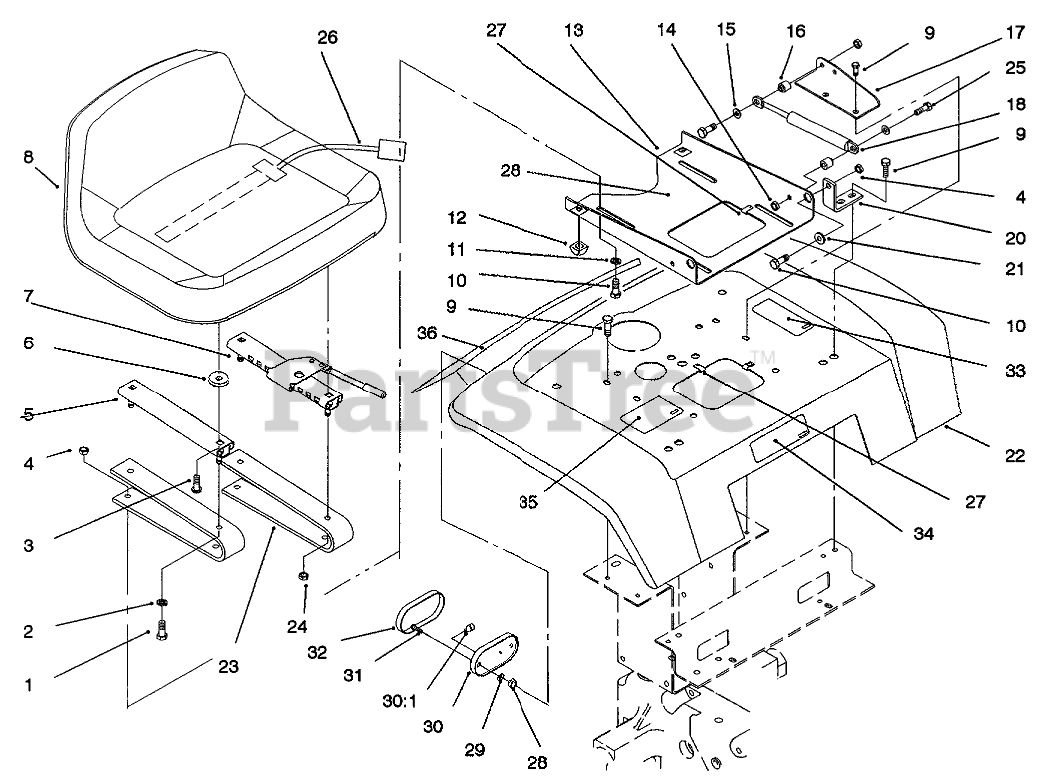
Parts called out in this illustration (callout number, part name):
1	SCREW-HH
2	WASHER-LOCK
4	NUT-LOCK, NI
6	SPACER-NYLON
8	SEAT
9	Bolt
10	SCREW-HH
11	WASHER-PLAIN
12	BUMPER SJ5514 BLACK
13	PLT-SEAT PIVT (BLACK)
14	NUT-HEX
15	WASHER-FLAT
16	SPACER
17	Bracket-Gas Spring
18	GAS SPRING
20	BRACKET-PIVOT
21	BUSHING
23	SPRING SEAT (BLACK)
25	SCREW-HH
26	SWITCH-SEAT
27	SPEED CLIP
28	NUT-LOCK, NI
29	WASHER-LOCK, INT
30	BASE-TAIL LIGHT
30:1	LIGHT BULB
31	SCREW-PPH
32	LENS-TAIL LIGHT
35	DECAL - DO NOT TOW
36	DECAL - REAR FENDER
